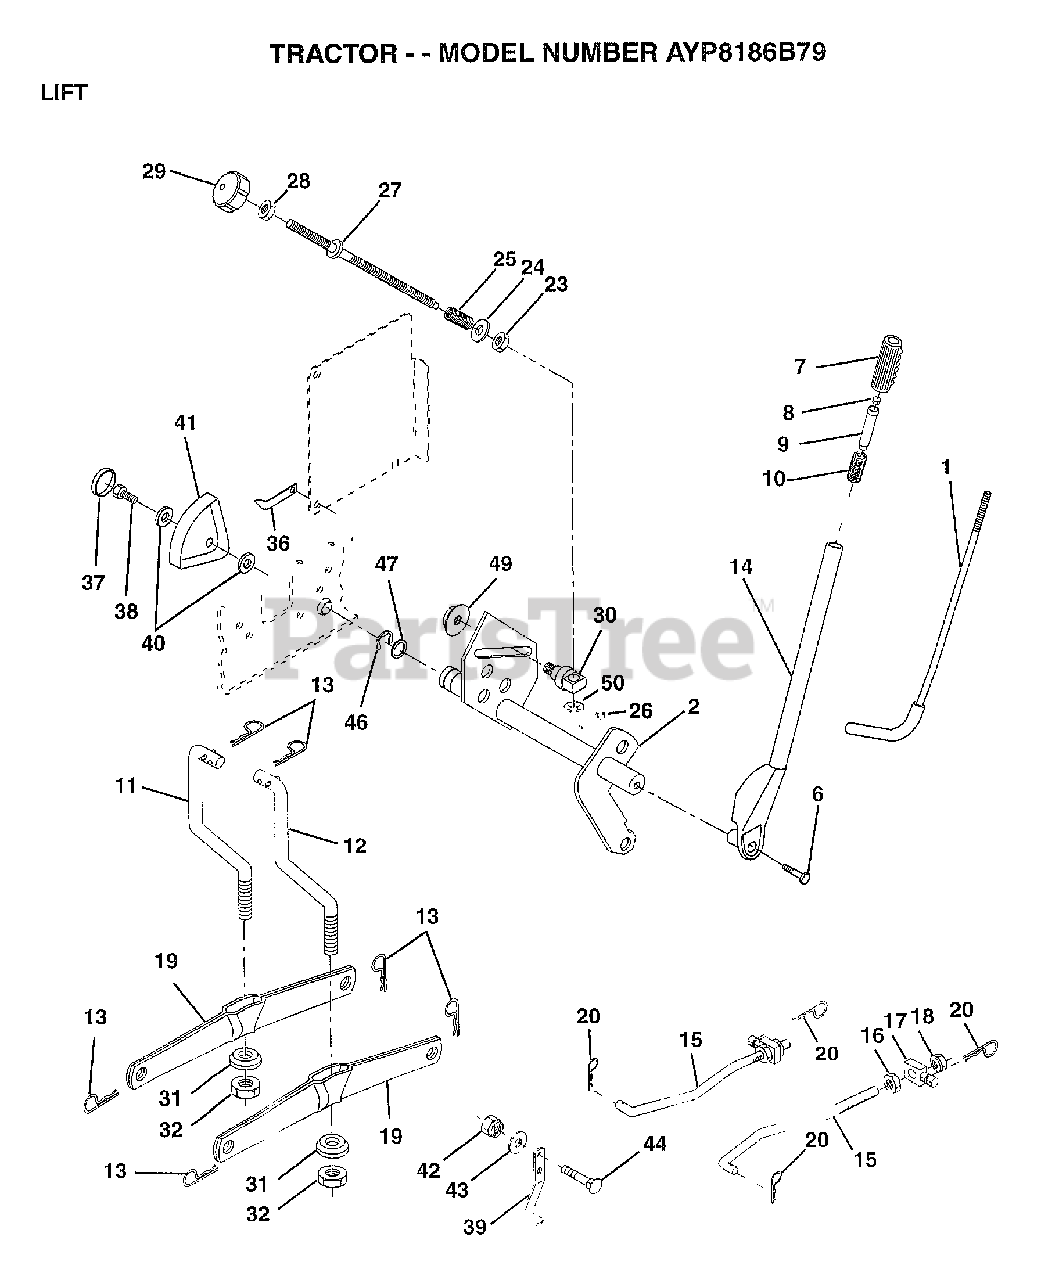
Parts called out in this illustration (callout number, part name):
1	LEVER ROD LT
2	SHAFT LIFT W/IND
6	"BOLT,HEX"
7	GRIP
10	SPRING T
11	LINK.LIFT.LH.GTV
12	LINK.LIFT.RH.GTV.
15	LINK.FRONT
16	NUT
17	TRUNION
18	NUT.LK.W/WSH.1/2.
19	ARM SUSP REAR
20	RETAINER.SPRING
23	NUT T
24	WASHER
25	SPRING T
28	NUT
29	KNOB INF 3/8-16
30	TRUNNION
31	BEARING PVT LH
32	NUT.CROWNLOCK.3/8
36	POINTER-INDICAT
37	"PLUG,HOLE"
38	SCREW
39	STOP.OVER.CENTER
40	WASHER
41	HEIGHT INDICATOR
43	WASHER GT
44	BOLT
46	E-RING
47	WASHER
49	NUT.HXFLG.LOCK.
50	NUT PUSH M
